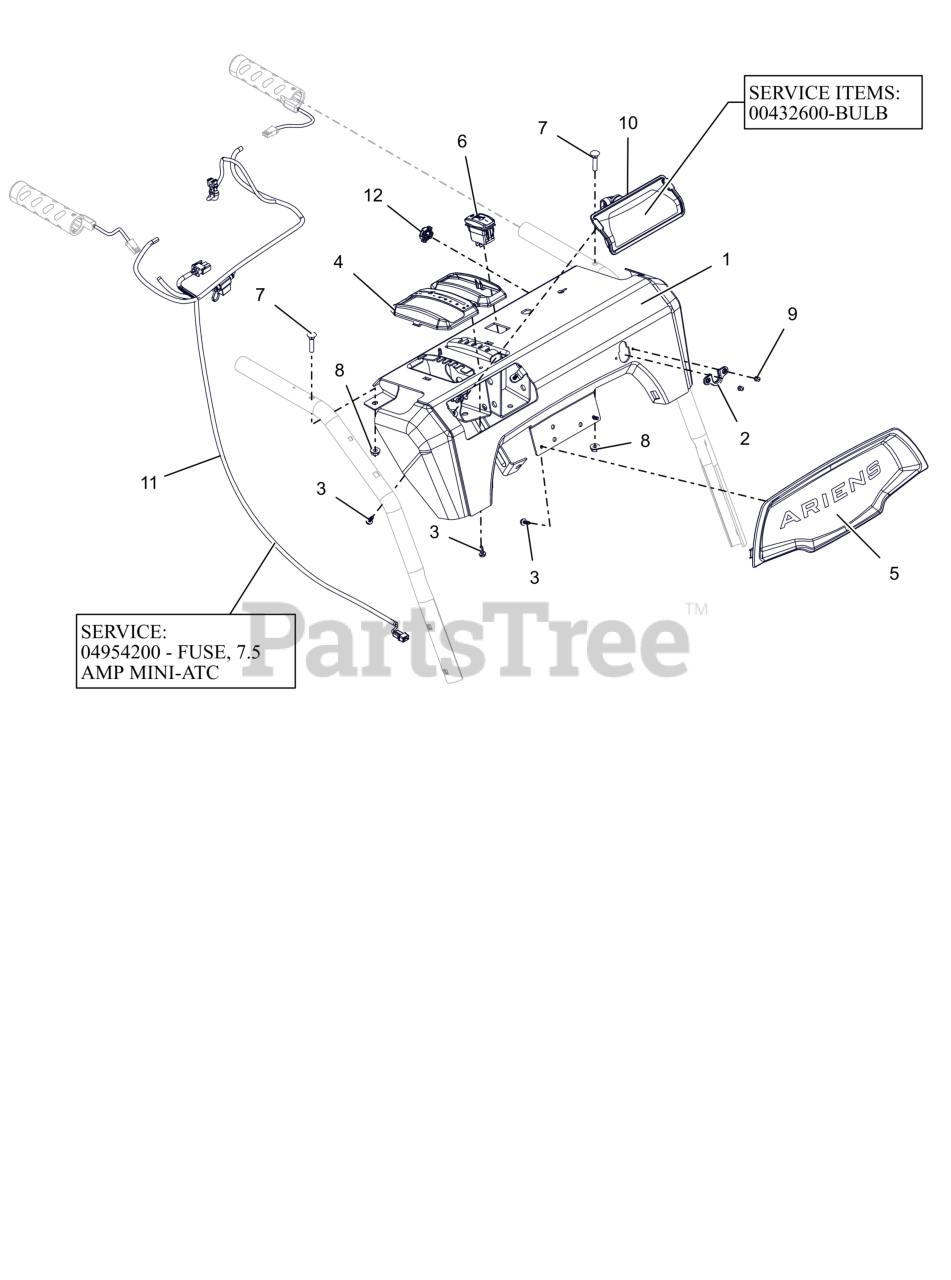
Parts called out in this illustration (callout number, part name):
1	PANEL, CONTROL-EFI ID W/DECAL
2	GROMMET, CABLE, QUICK TURN 2
3	SCR, PLASTIC #10X.50
4	BEZEL, SHIFT - FRICTION SNOW
5	BEZEL, DASH - ARIENS LG DASH
6	SWITCH,ROCKER SPST-ON/OFF
7	BLT-RDHDXLSQNK.25-20X1.25 G5ZC
8	NUT-LK-CTR-FLG .25-20 ZC120
9	RVT-POP #43 .125X.313 STL ZINC
10	HEADLIGHT ASY, HALO 20W 2SHOT
11	HARNESS,LIGHT&WARMER - EFI
12	CRANK BUSHING, NYLON CHUTE BK
